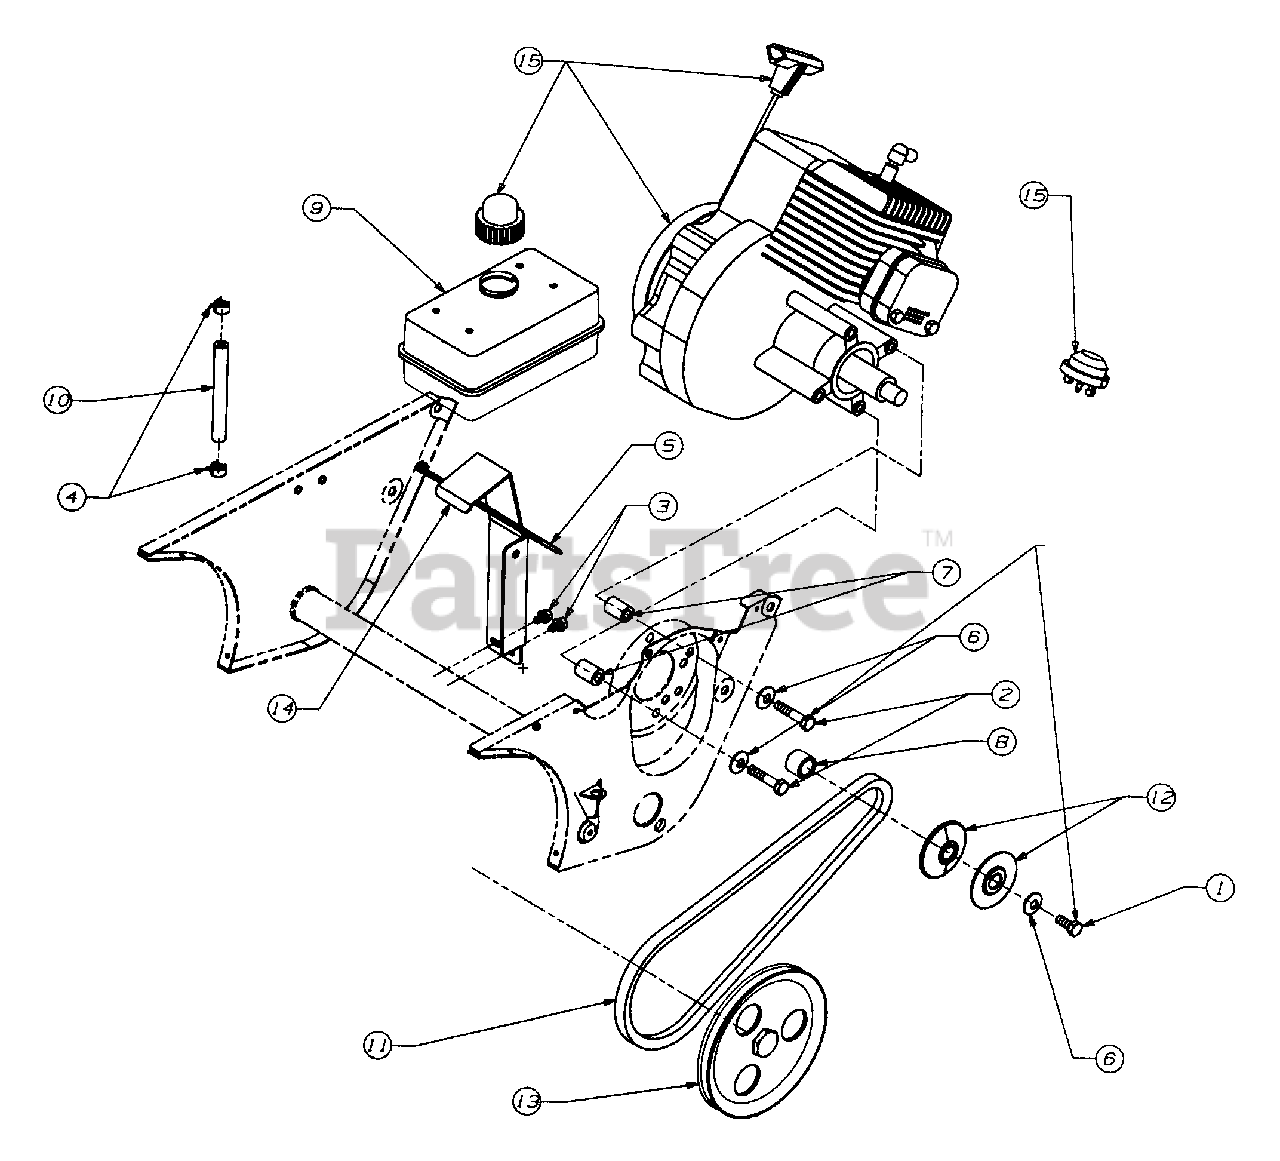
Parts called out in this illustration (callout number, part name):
1	Screw Hex
2	Screw Hex
3	Screw Hex
4	Clamp Hose
5	Tie Cable
6	Washer Bell
7	Spacer
8	Spacer
9	Tank - Gas (1 Qt.)
10	Hose - Fuel Line (12")
11	V-Belt
12	Pulley Half V
